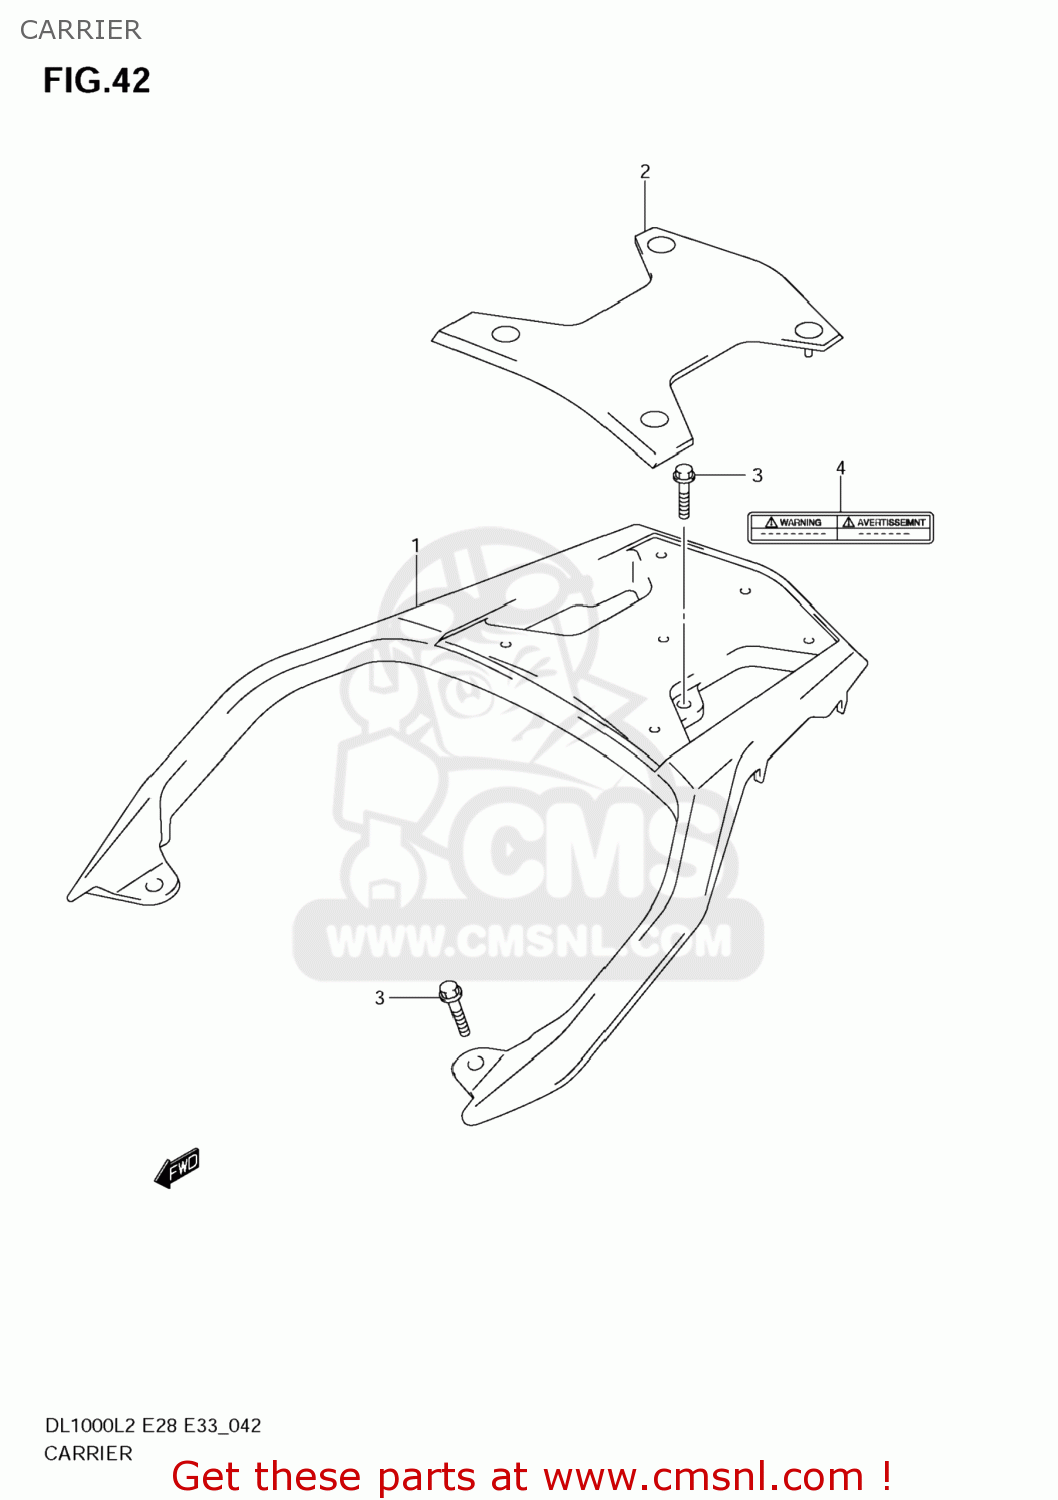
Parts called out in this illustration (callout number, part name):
1	CARRIER,SPORT
2	MAT,SPORT CARRIER
3	BOLT(8X35)
4	LABEL,CARRIER
